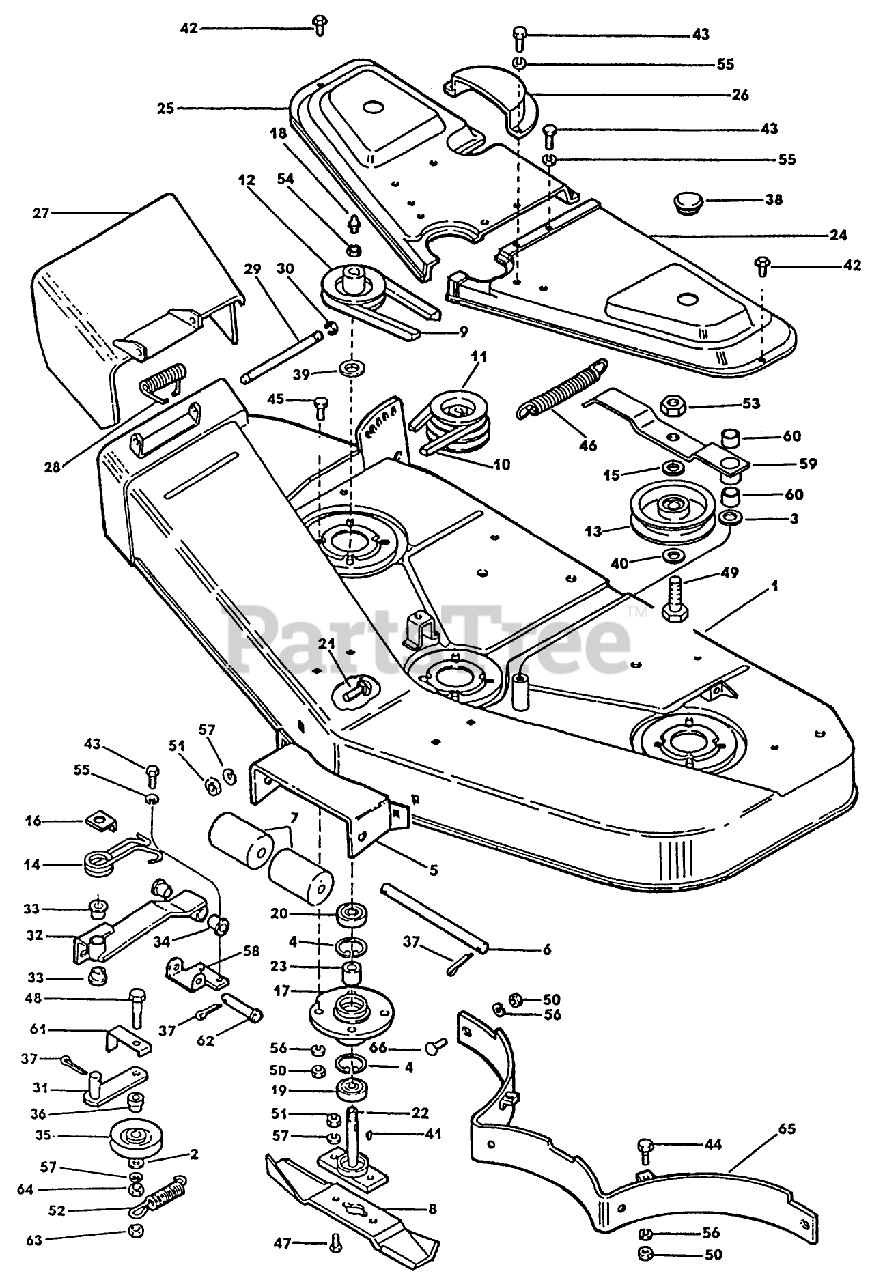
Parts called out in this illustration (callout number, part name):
2	WASHER
6	SHAFT
7	ROLLER
9	V-BELT
10	V-BELT (DRIVE)
13	PULLEY - IDLER
14	SPRING
17	HOUSING-SPINDLE S
22	SPINDLE ASSEMBLY
28	SPRING - CHUTE
29	SHAFT - CHUTE
30	E-RING
32	PIVOT ASSEMBLY
33	BUSHING
34	BUSHING
35	PULLEY - V-IDLER
36	SPACER
38	PLUG - BELT COVER
39	SPACER
42	SCREW-THREAD FRMG
43	SCREW-HH
44	SCREW - HEX
45	SCREW
46	SPRING
48	SCREW-HH
50	NUT SS
51	NUT
52	SPRING - TENSION *B
54	LOCKNUT-SPECIAL
57	WASHER
60	BEARING-SLEEVE
61	GUIDE - BELT
62	PIN - CLEVIS
63	NUT
64	NUT-HEX JAM
